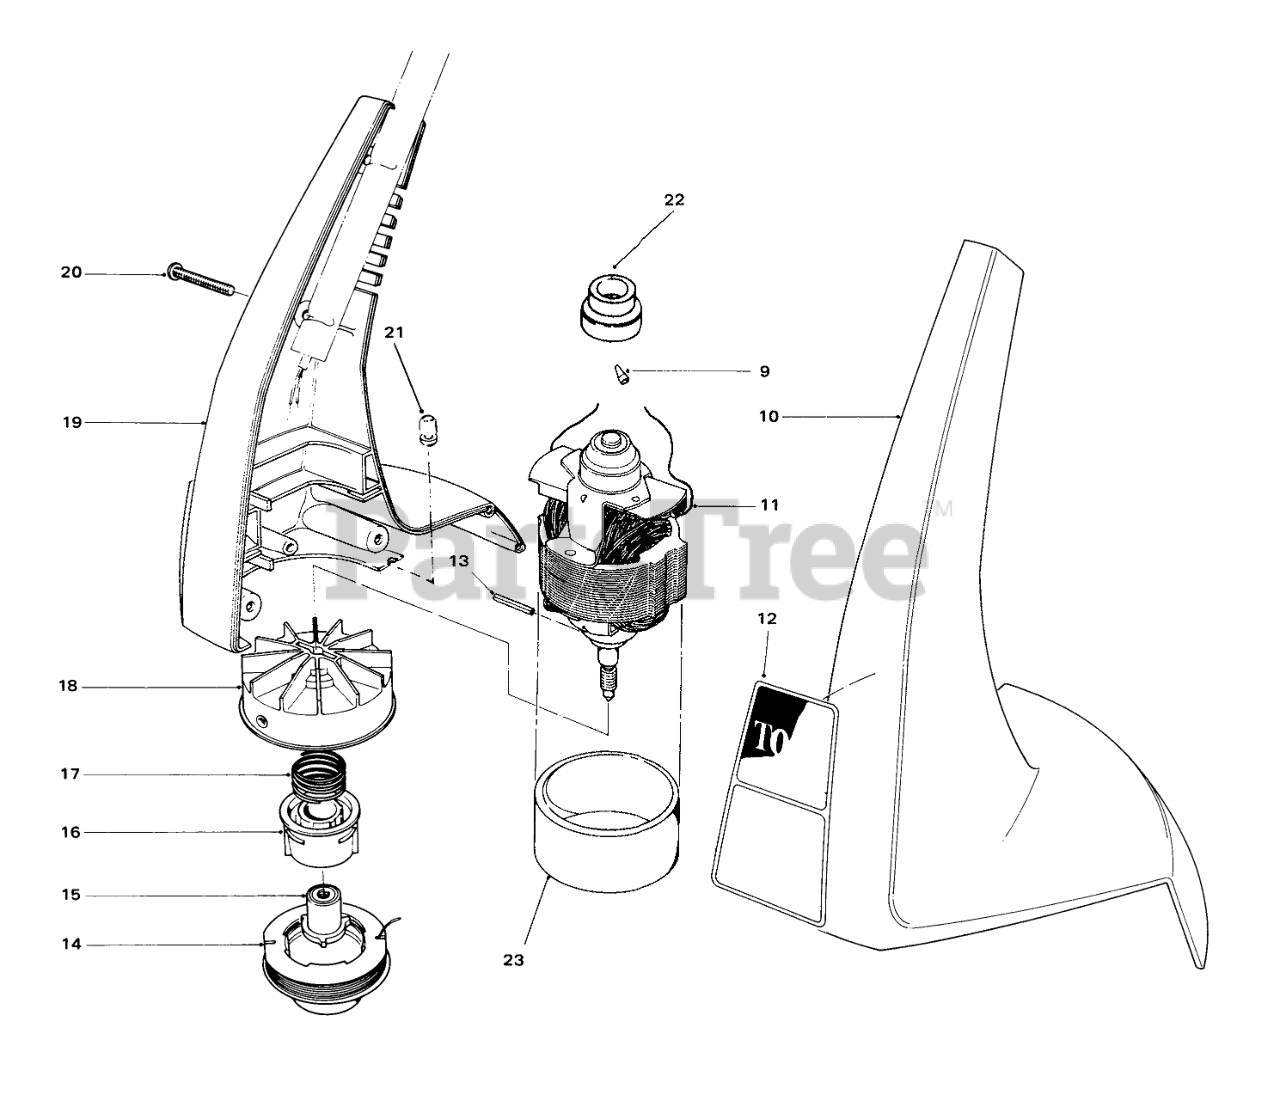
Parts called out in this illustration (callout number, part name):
9	Wire Connector
10	Left Hand Housing
11	Motor
12	DECAL 900
13	COIL PIN
14	Prewound Spool
15	Driver
16	CORE - SPOOL
17	SPRING-COMPRESSION
18	FAN HUB ASM
19	Right Hand Housing
20	Screw
21	GROMMET
22	Adapter-Motor
23	DAMPENING SLEEVE
